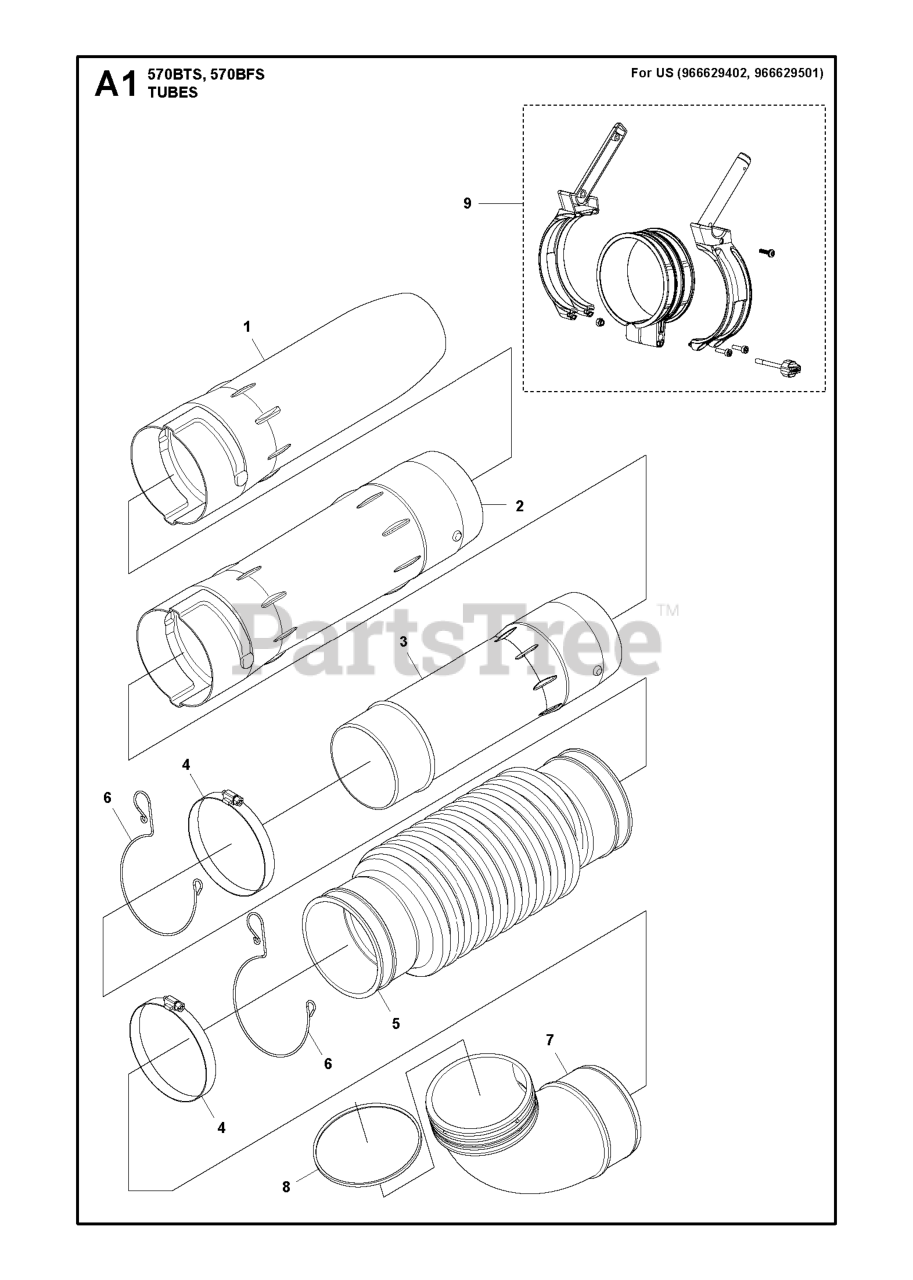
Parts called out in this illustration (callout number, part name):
2	PIPE STRAIGHT
4	CLAMP(F115)
5	HOSE
7	PIPE ELBOW
